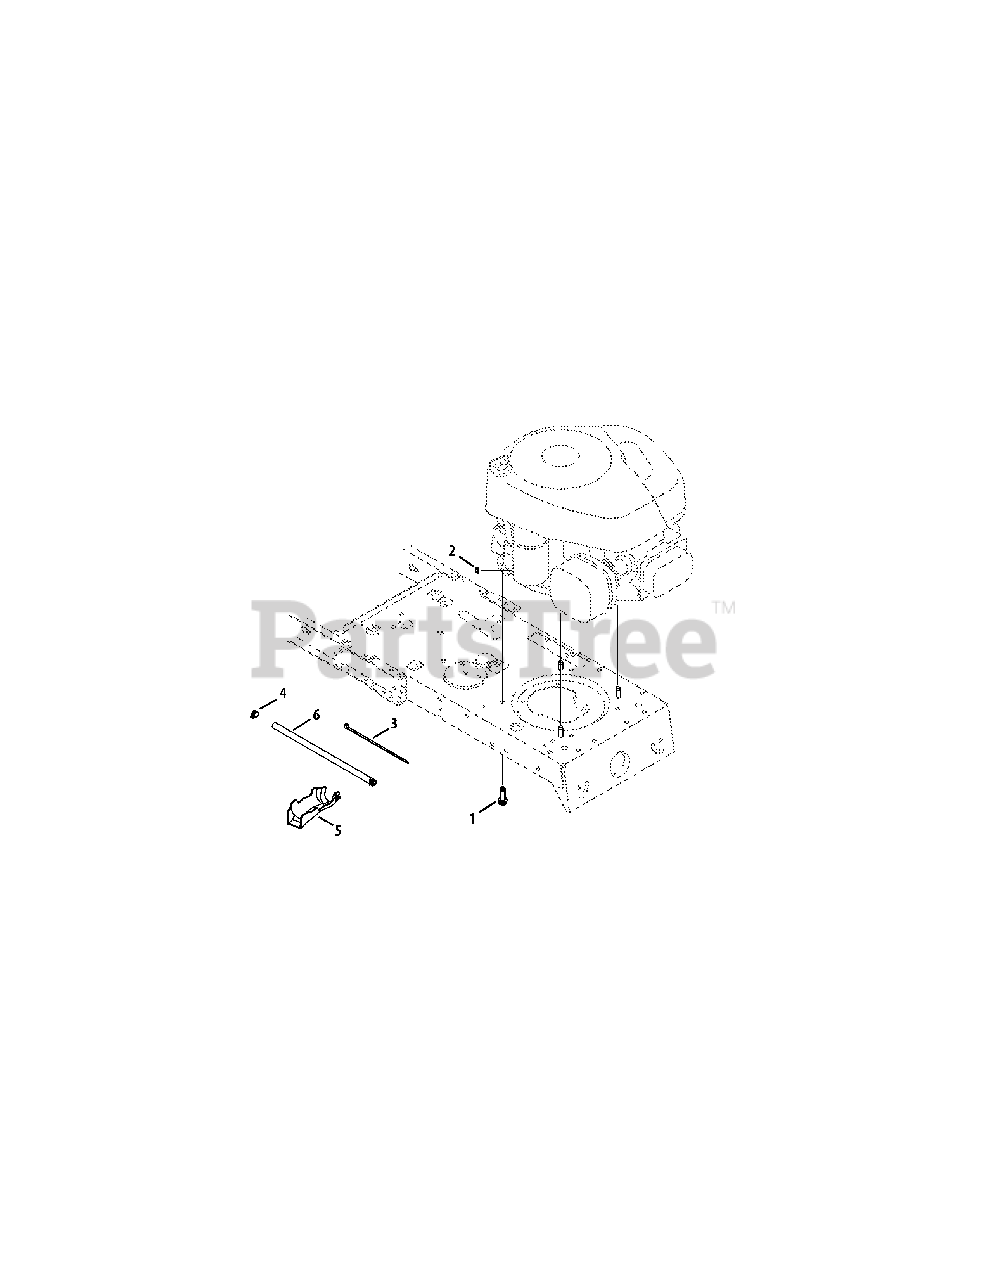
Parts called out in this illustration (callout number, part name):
1	Screw, 3/8-16 x 1.0
2	Sems Nut, 1/4-20
3	Cable Tie
4	Clamp Hose, .490 diameter
5	Oil Drain Sleeve
6	Fuel Hose, Low Permeation
